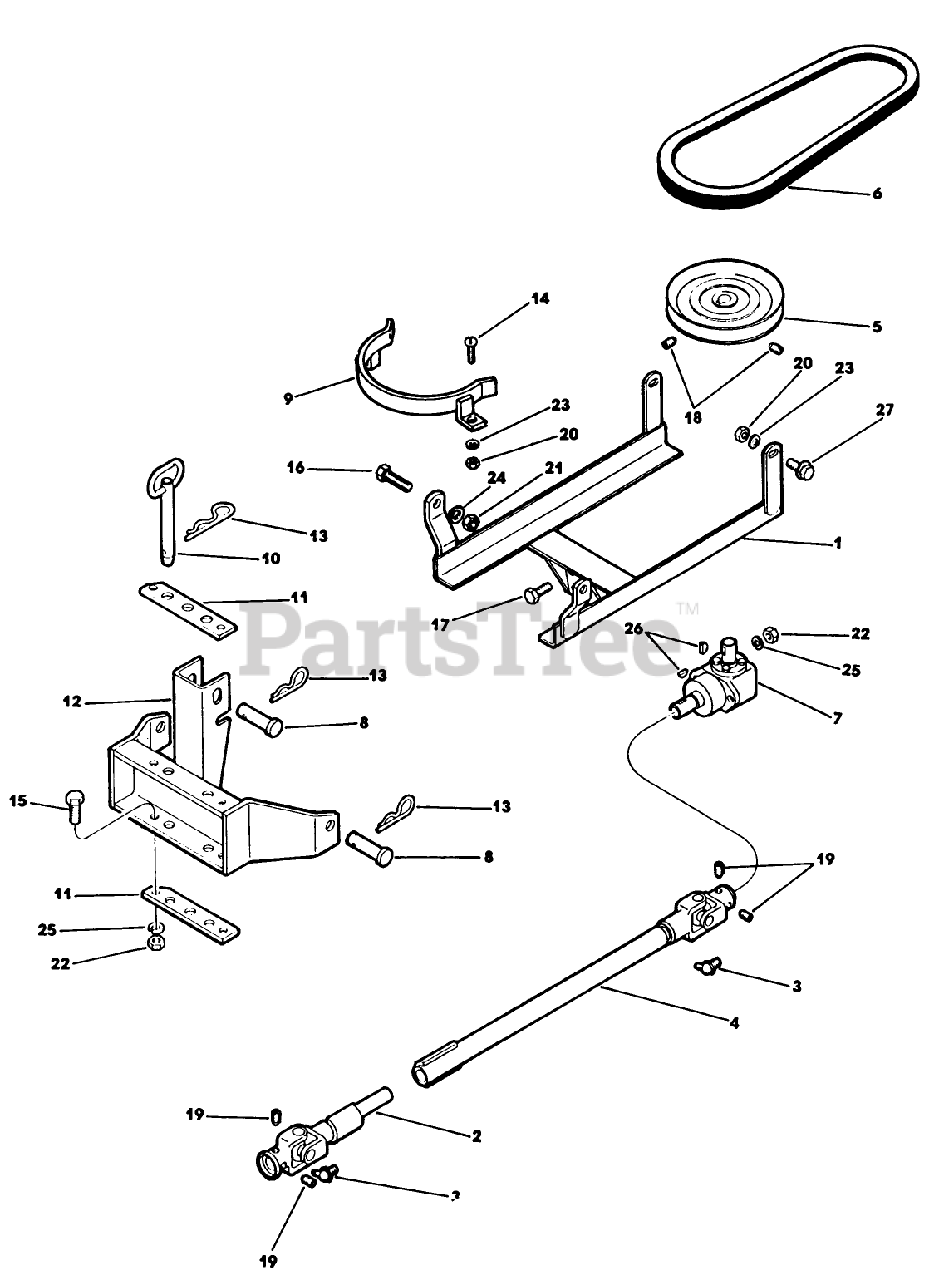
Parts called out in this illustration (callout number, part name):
2	UNI COUPLING
4	DRIVE TUBE AY *B
7	GEAR BOX
10	PIN AY. - HITCH
18	SET SCREW
